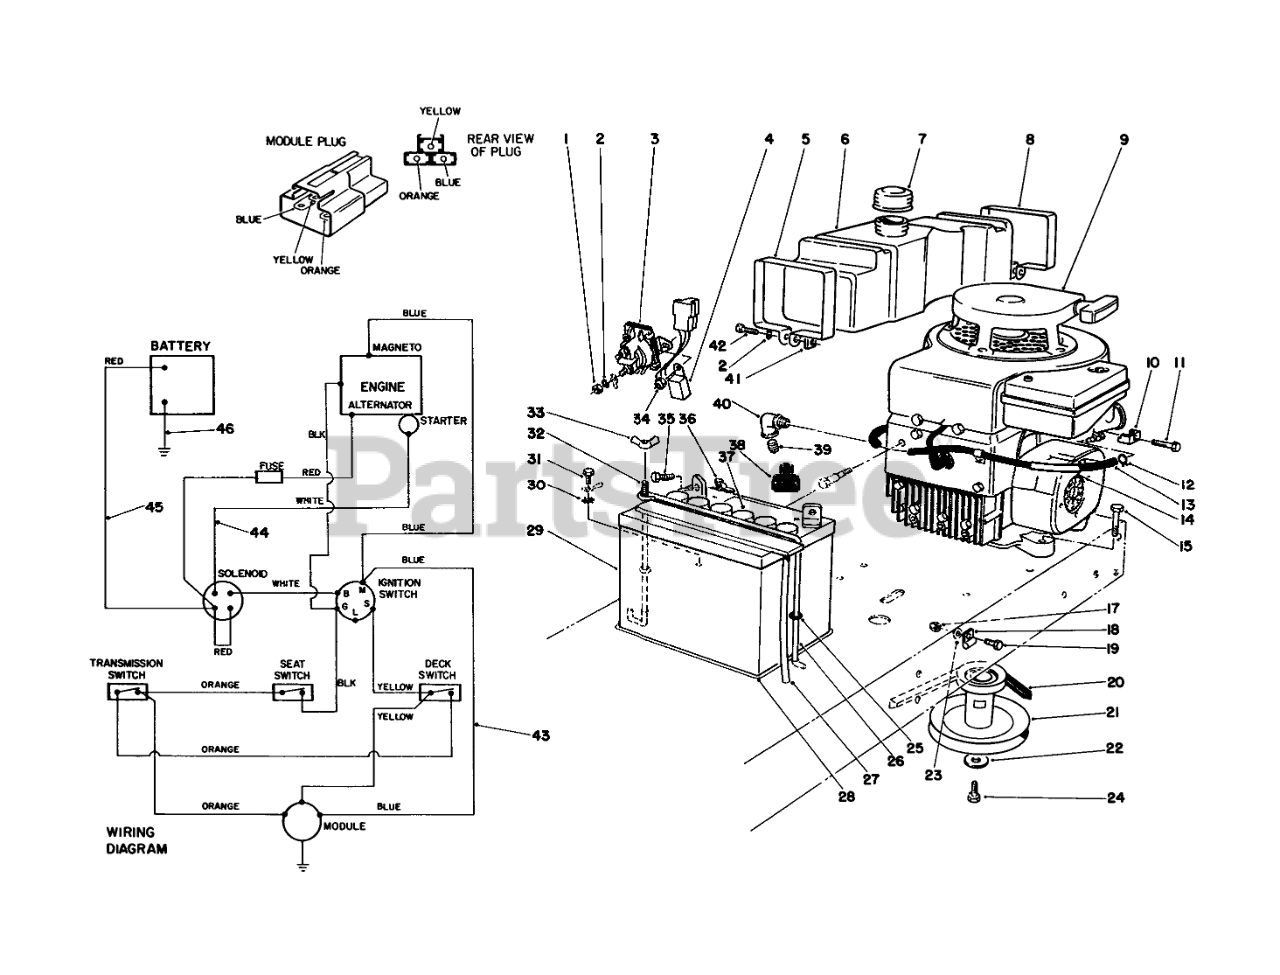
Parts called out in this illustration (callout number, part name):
1	NUT-JAM
2	WASHER-LOCK
3	SOLENOID
4	Module Interlock
5	Retainer-Front
6	TANK-5 QT GAS
7	GAS CAP ASM
8	Retainer-Rear
9	Engine-10 H.P. B & S
10	CLAMP-CASING
11	SCREW W ENGINE
12	CLAMP-HOSE
13	HOSE -RETURN
14	SUPPORT-FUEL LINE
15	SCREW-HH
17	NUT-LOCK, NI
18	CLAMP
19	SCREW-HH
20	V-BELT, TRACTION
21	ENGINE PULLEY ASM
22	WASHER-FLAT
23	WASHER-PLAIN
24	SCREW-HH
25	O-RING
26	HOLDDOWN-BATTERY
27	TUBE-BATT DRAIN/80-2600
28	PAD-SKID, ANTI
29	Battery
30	WASHER-LOCK, INTERNAL
31	SCREW-HWHTF
32	POST-BATTERY
33	NUT-WING
34	NUT-LOCK, NI
35	SCREW-HH
36	NUT-WING
37	CAP-BATTERY
38	BOOT-TERMINAL
39	3/8 PIPE PLUG
40	ELBOW-STREET, 90 DEG
41	NUT-SQUARE
42	SCREW-HSH
43	WIRING HARNESS
44	WIRE HARNESS
45	WIRE ASM
46	WIRE ASM(BATT/GRD.
